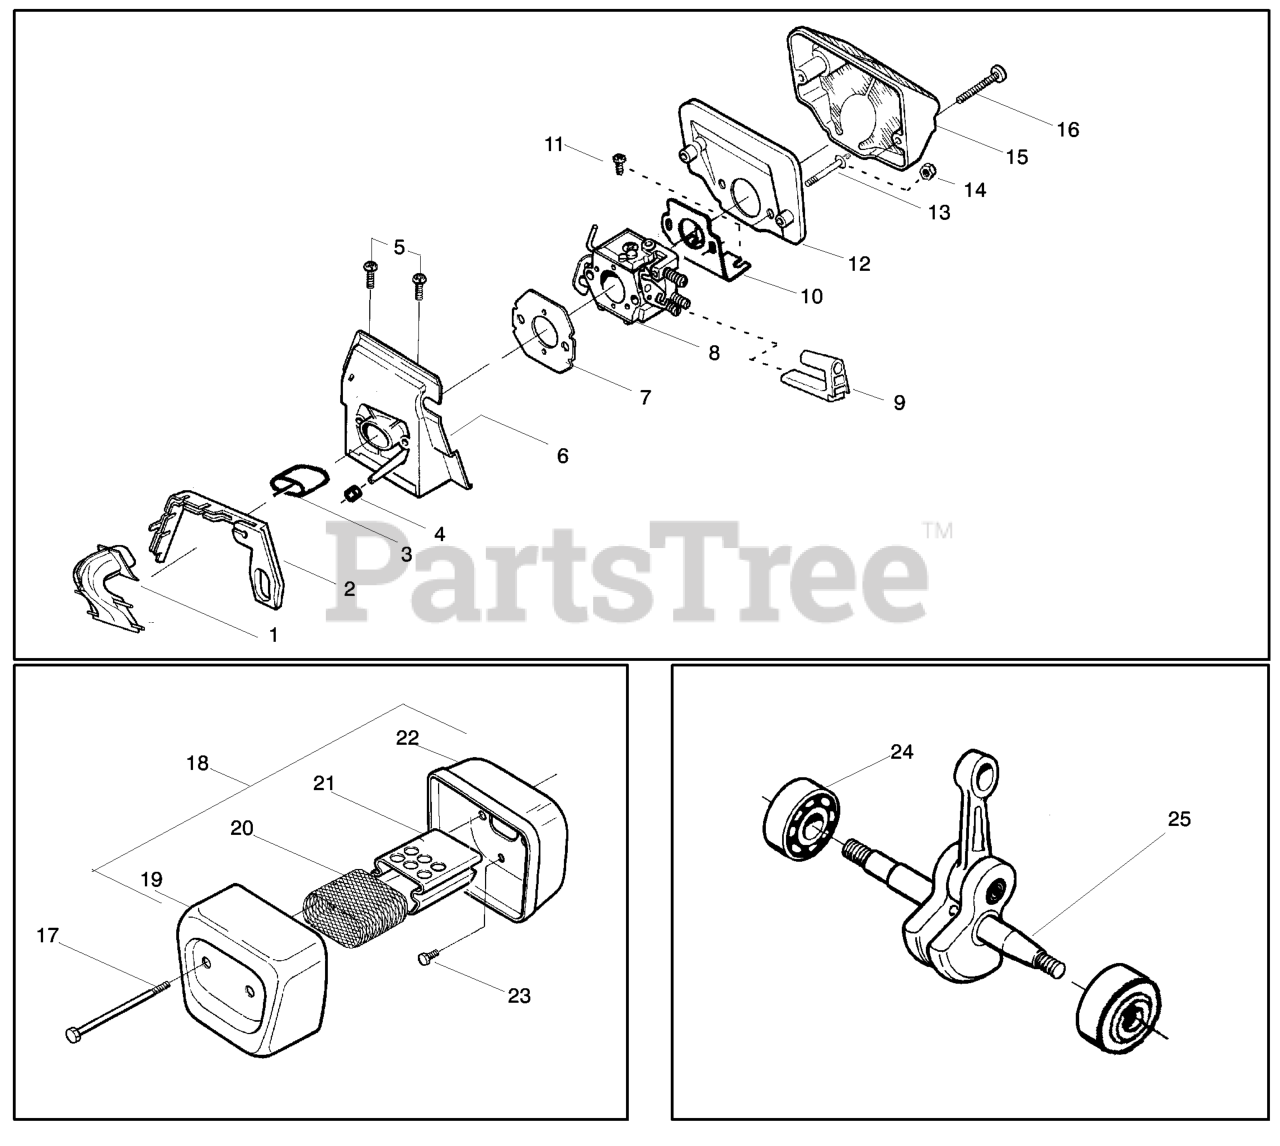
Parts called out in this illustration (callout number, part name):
1	INTAKE HORN
2	TURBO CLEAN SEAL
3	INTAKE PIPE
4	IMPULSE PIPE
6	CARB ADAPTOR
7	GSKT,CARB 36/41
8	Carburetor
8	CARBURETOR
8	CARBURETOR/EPA
8	CARB WT-660
9	Grommet-Final
12	AIR FILTER (BOTTOM)
13	STUD-CARBURETOR
15	AIR FILTER
18	MUFFLER KIT
19	SILENCER COVER
20	SPARK ARRESTOR 36/41
21	FLAME PROTECTOR
22	SILENCER BODY
23	BOLT-MUFFLER(SUPPORT)
24	Assy. -Bearing and Seal
25	CRANKSHAFT ASSY 36/41
